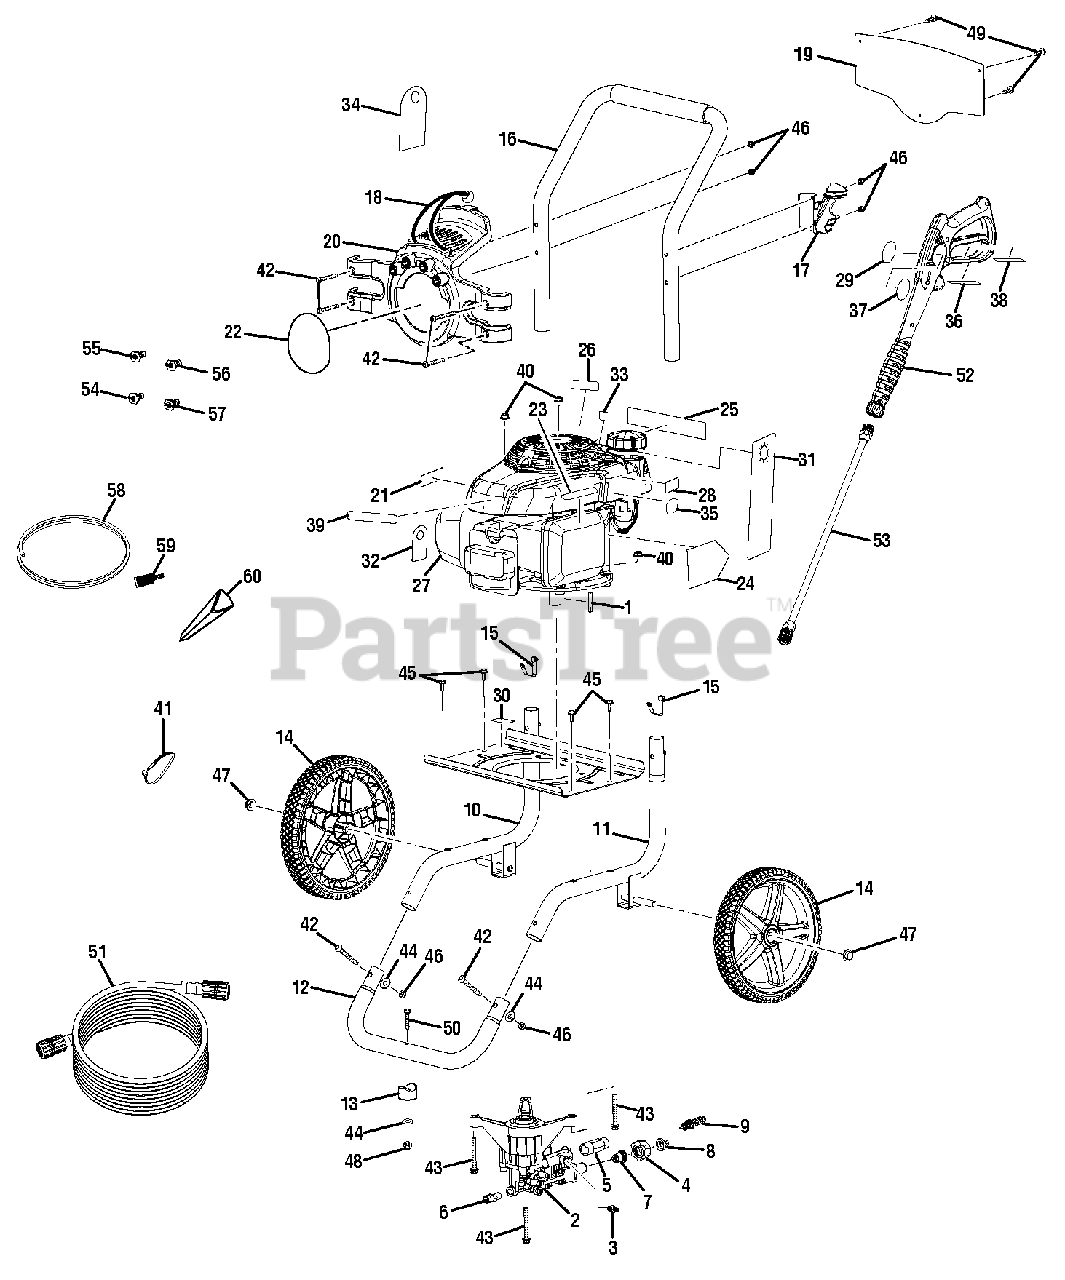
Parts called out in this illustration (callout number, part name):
1	Output Shaft Key
2	Pump
3	Detergent Injector Assembly
5	Outlet Tube
6	Thermal Release Valve
8	Filter Screen
9	Unloader Assembly
10	Main Frame Assembly
11	Main Frame Assembly
12	Front Frame Assembly
14	Wheel
15	Spring Clip
16	Handle Assembly
17	Trigger Handle Holder
18	Bungee Cord Assembly
19	Quick Start Panel
20	Hose and Nozzle Holder
21	Hot Surface Label
22	Performance Label
23	Inquiries Label
24	Choke Label
25	Danger Label (Eng/Sp)
26	Combustion Label
28	Do Not Mix Label
29	Logo Label
30	Oil Fill Location Label
31	Danger Hangtag
32	Dipstick Hangtag
33	No E85 Label
34	Nozzle Hangtag
35	Engine On/Off Label
36	Warning Label (Eng/Sp)
37	Warning Label
38	Wand Rating Label
39	Honda Brand Label
40	Lock Nut (M8 x 1.25)
42	Screw (M6 x 48 mm, T30 Torx Hd.)
43	Bolt (M8 x 60 mm, Hex Flange Hd.)
44	Washer (1/4 in.)
45	Bolt (M6 x 16 mm, Hex Flange Hd.)
46	Lock Nut (M6)
47	Push Cap Nut (1/2 in.)
48	Lock Nut (1/4-20)
49	Screw (#6-20 x 3/8 in.)
50	Screw (1/4-20 x 1.85 in., T30 Torx Hd.).
51	High Pressure Hose
52	Trigger Handle Assembly
53	Spray Wand Assembly
54	0deg Nozzle
55	25deg Nozzle
56	40deg Nozzle
57	Soap Nozzle (Blue)
58	Chemical Siphon Tube
59	Chemical Siphon Filter
